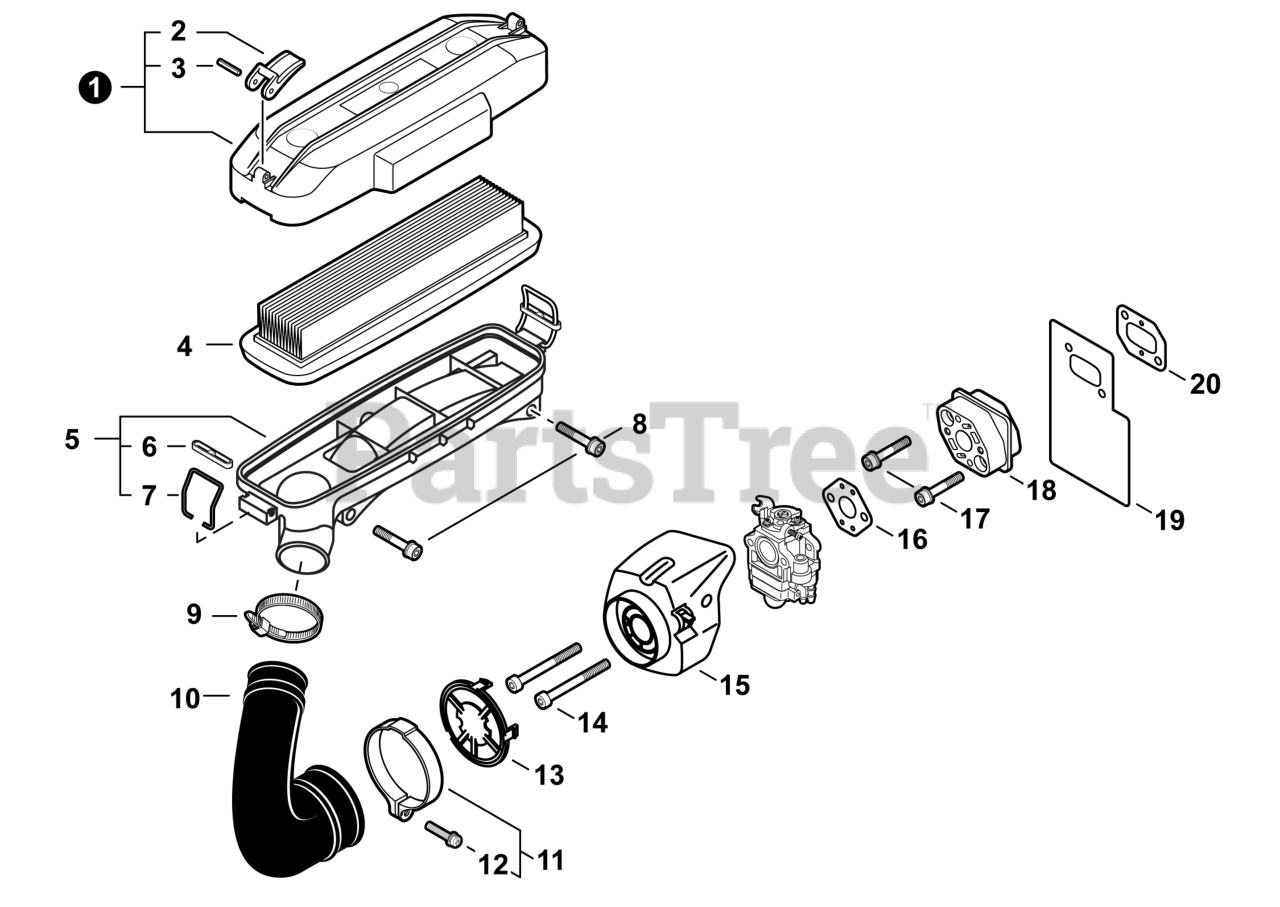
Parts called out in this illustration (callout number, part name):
1	COVER, AIR FILTER
2	LATCH, FILTER COVER
3	PIN, SPRING 3×25
4	FILTER, AIR
5	CASE ASSY, AIR FILTER
8	SCREW 5×35
9	CLAMP 33 MM /57 MM
10	PIPE, INTAKE
11	CLAMP KIT
12	SCREW 5×25
13	PLATE, PREVENT
14	BOLT 5×55
15	CASE ASSY, AIR FILTER
16	GASKET, INTAKE
17	BOLT, FLANGE 5X25
18	INSULATOR, INTAKE
19	HEAT SHIELD, INTAKE
20	GASKET, INTAKE
21	GASKET KIT
